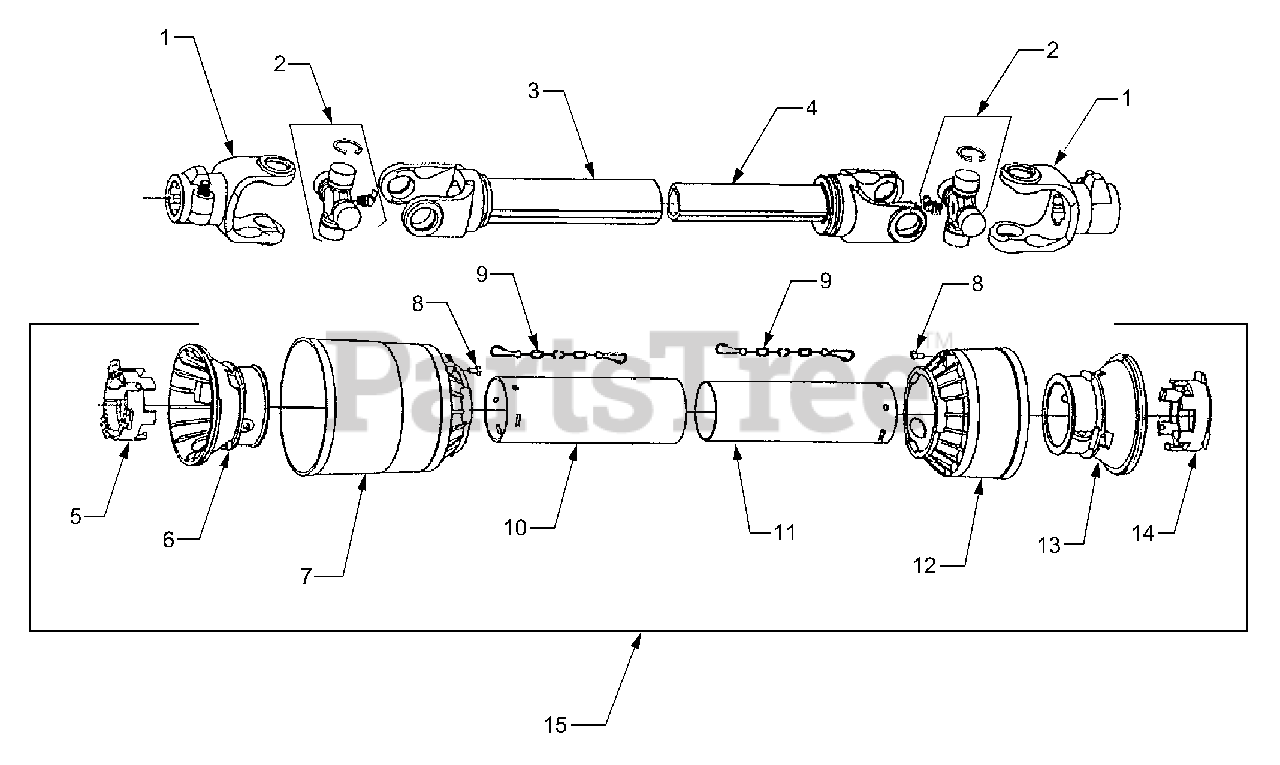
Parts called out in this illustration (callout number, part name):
1	Yoke Assembly
2	Cross and Bearing
3	Outside Tube w/Yoke
4	Inside Tube w/Yoke
6	Outer Tube Ridged Cone
10	Outer Shield
11	Inner Shield
13	Inner Tube Ridged Cone
15	Complete PTO Shaft Shield
